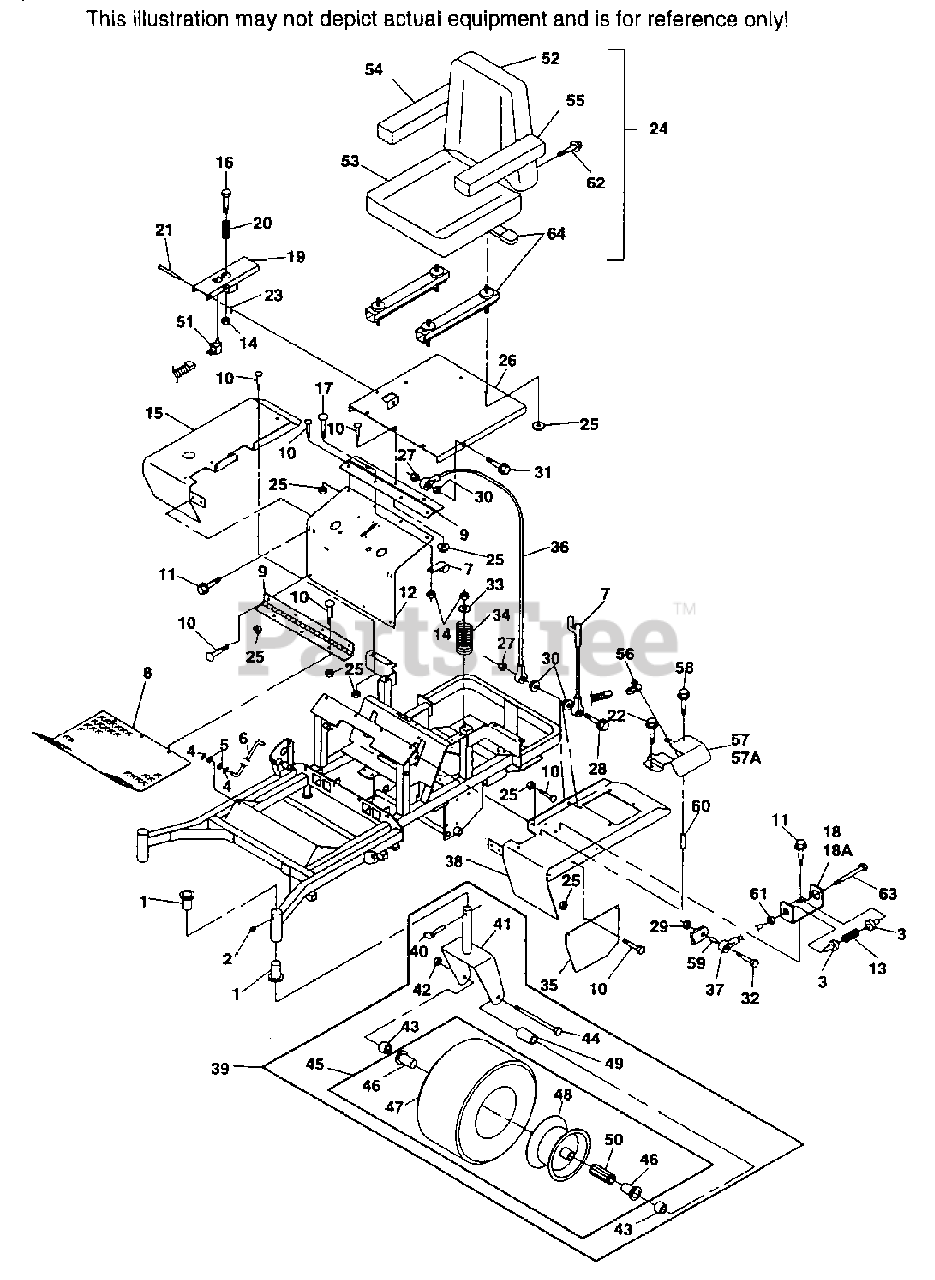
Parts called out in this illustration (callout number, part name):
1	BUSHING
2	GREASE FITTING
3	BUSHING, SPRING KEEPER
4	HAIR PIN, .08 DIAMETER
5	FLATWASHER, 3/8" SPECIAL
6	ROD, FOOT PLATE LATCH
7	CABLE, SEAT STOP
8	FOOT PLATE
9	HINGE
11	CAP SCREW, 5/16-18 X 3/4" SERRATED FLANGE HEX
12	KICK PLATE
13	NEUTRAL RETURN SPRING
14	ELASTIC STOP NUT, 5/16-18
15	FENDER ASSEMBLY, RH(WITH DECAL)
18	RETAINER, NEUTRAL SPRING, LH
18A	RETAINER, NEUTRAL SPRING, RH
19	SEAT SWITCH BRACKET
20	SPRING
21	CLEVIS PIN
22	CAP SCREW, 5/16-18 X 1/2" SERRATED FLANGE HEX
23	HAIR PIN COTTER
24	SEAT ASSEMBLY W/ ADJUSTER RAILS
25	NUT, 5/16-18 SERRATED FLANGE HEX HEAD
26	SEAT BASE
27	HEX NUT, 1/4-20 ELASTIC STOP
28	CAPSCREW 1/4-20 X 1-1/2" SERRATED FLANGE HEX
30	NUT, 1/4-20 SERRATED FLANGE HEX HEAD
31	CAP SCREW, 1/4-20 X 1" SERRATED FLANGE HEX
34	SEAT SPRING
35	FENDER PANEL, LH
36	CABLE, SEAT STOP
37	BALL JOINT, NEUTRAL
38	FENDER - LH
39	CASTER WHEEL YOKE ASSEMBLY, COMPLETE
40	QUICK PIN
41	CASTER WHEEL YOKE
43	SPACER
45	WHEEL ASSEMBLY, COMPLETE
46	RETAINER
47	TIRE ONLY
48	RIM ONLY
49	SLEEVE
50	ROLLER BEARING
51	SEAT SWITCH
52	SEAT BACK CUSHION
53	SEAT BOTTOM CUSHION ASSEMBLY
54	ARM PAD, RH
55	ARM PAD, LH
56	NEUTRAL INTERLOCK SWITCH
57	NEUTRAL LOCK BRACKET, RH
57A	NEUTRAL LOCK BRACKET, LH
58	CAP SCREW, 5/16-18 X 2-3/4" SERRATED FLANGE
59	SPACER NEUTRAL SPRING
60	SPACER, NEUTRAL LOCK BRACKET
61	HEX NUT, 3/8-24 UNF
62	HEX HEAD SCREW W/WASHER, 1/4-20 X 3/4"
63	HEX HEAD BOLT, 3/8-24 X 6-1/2", UNF
64	SEAT ADJUSTMENT; TRACK SET
